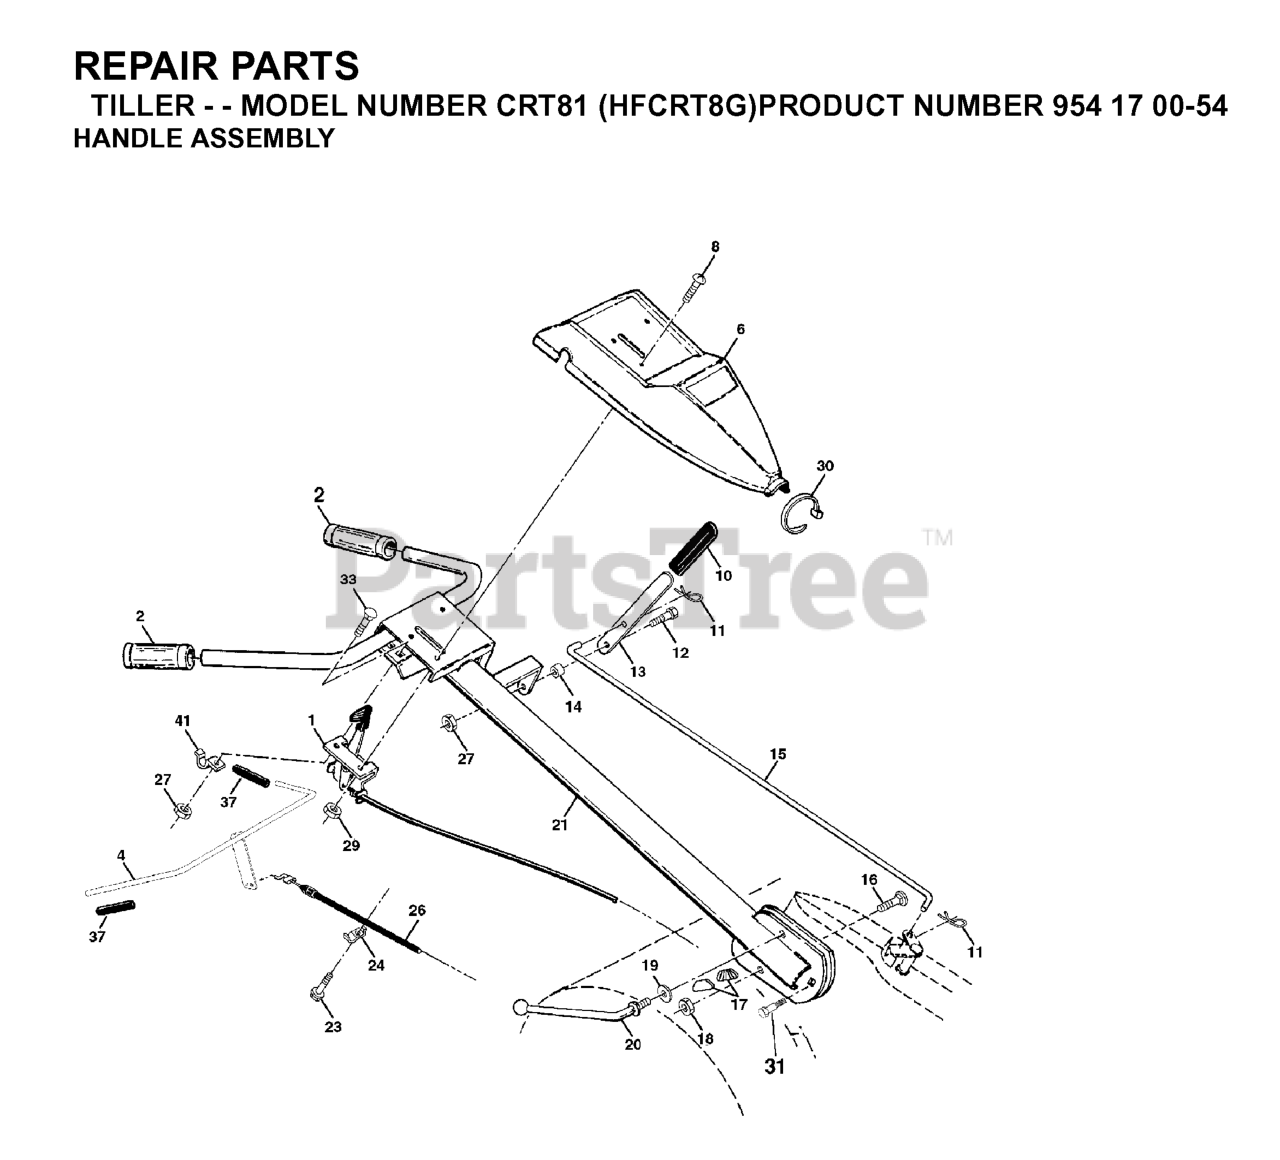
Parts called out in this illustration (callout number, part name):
1	THROTTLE.CONTROL.
2	KIT.GRIP.HANDLE.5.00.BLK.VINYL
4	CONTROL BAR ASSY
6	RP CONTROL PANEL
8	SCREW.PNHD.10-24
10	GRIP T
11	RETAINER M
12	SHOULDER BOLT ST
13	SHIFT HANDLE CRT
14	GROMMET.RUBBER.CRT.TILLER
15	ROD.SHIFT.YARD PRO.UNIVERSAL.
16	BOLT D
17	LOCK.HANDLE.CRT
19	WASHER CRT
20	LEVER.LOCK.CRT
21	REPL BY 532 1805-17
23	TAPPING SCREW
24	CONDUIT.CLIP.PLATED
26	CABLE.CLUTCH
27	NUT T
29	NUT **
30	TIE CABLE CRT
31	BOLT.PIVOT
32	LOCK HANDLE
37	GRIP BAR CRT(1)
41	CLAMP.BAR.CRT.BLACK
